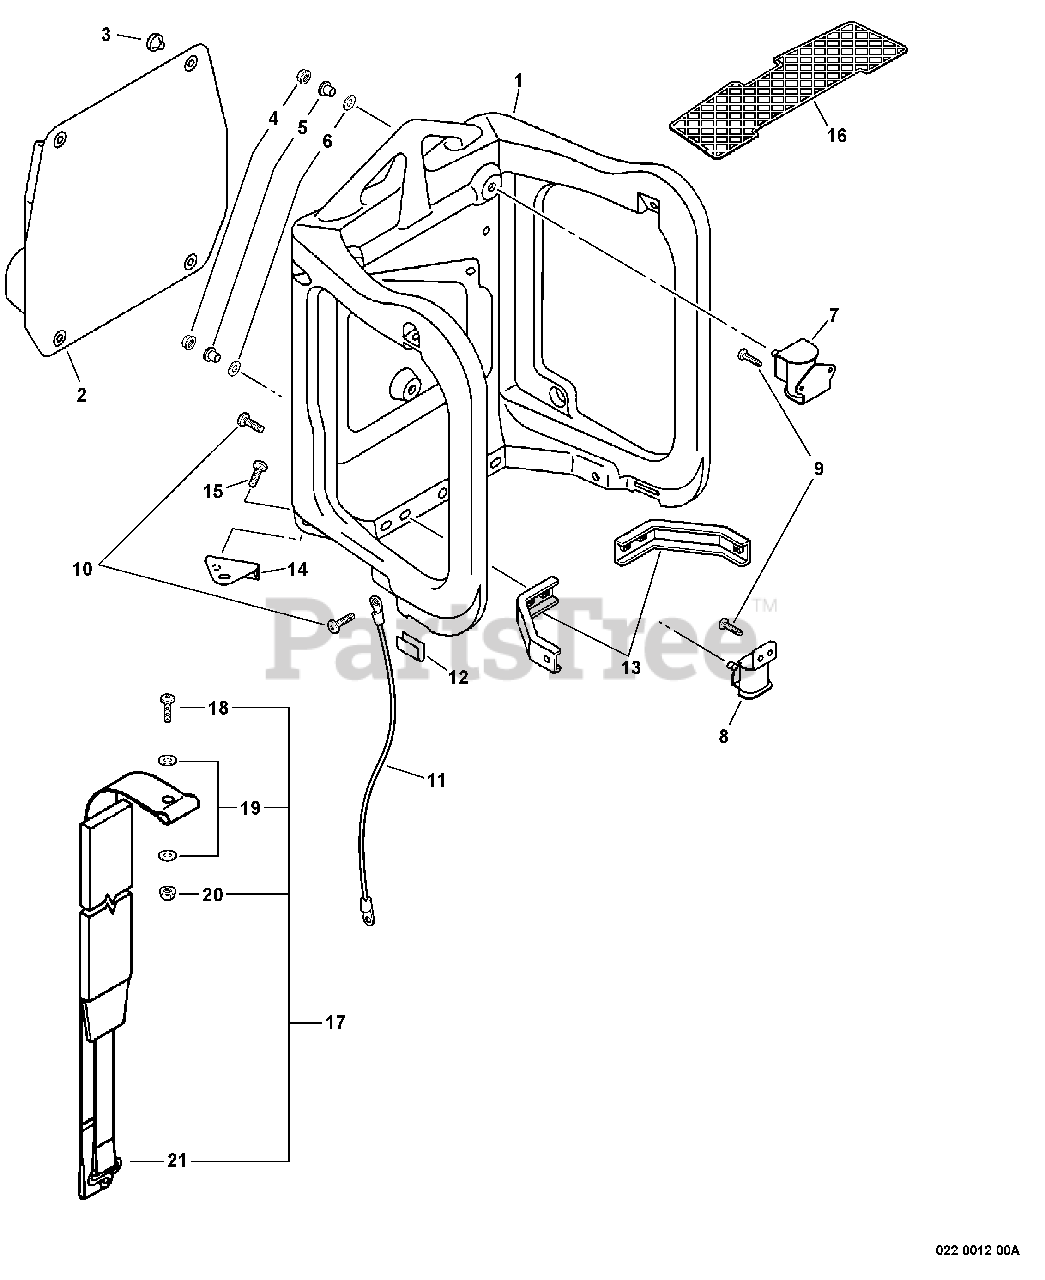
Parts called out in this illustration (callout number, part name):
1	FRAME, BACKPACK
2	CUSHION, BACKPACK
4	NUT - 5 -- FLANGE
6	WASHER - RUBBER
8	CUSHION
9	SCREW - 5X16 -- TAPPING
10	SCREW - 5X14
11	LEAD - GROUND
12	BUMPER
13	CONNECTOR, FRAME
14	BRACKET, HANGER
15	SCREW - 5X20
16	GAURD, DEBRIS
17	BACKPACK STRAP ASSY
18	SCREW - 5X14
20	NUT - 5 -- FLANGE
